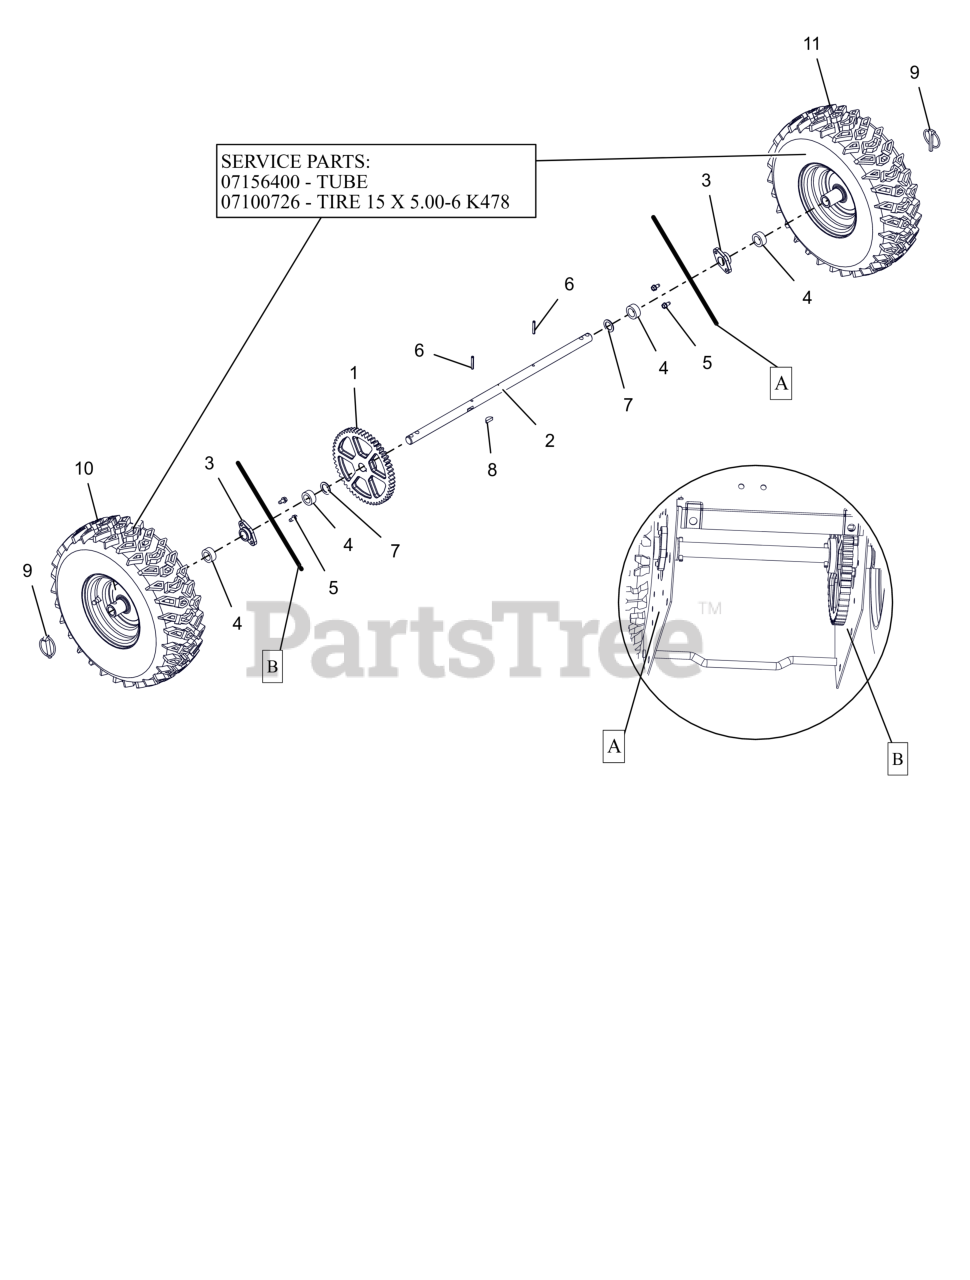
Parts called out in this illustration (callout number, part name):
1	SPUR GEAR, 54T .75ID X 6.75PD
2	AXLE, COMPACT
3	BSHG .75X1.125X.65
4	BSHG-SLV .766 X 1.125 X .500
5	SCR-TAP .25-20X.50 HWH ZCC
6	PIN-ROLL .188X1.25
7	WSHR, FLT .754X1.125X.062 ZCC
8	KEY-WDRF .25X.750X.313 SAE91
9	PIN-LOK .31X1.75
10	TIRE/WHEEL,RH 15X5.00-6 PIN T2
11	TIRE/WHEEL,LH 15X5.00-6 PIN T2
12	SNOW TIRE, 15/5.00-6 K478 DIRECTIONAL
13	TIRE TUBE, 15/5.00-6 4 PLY TR13 STRAIGHT VALVE
